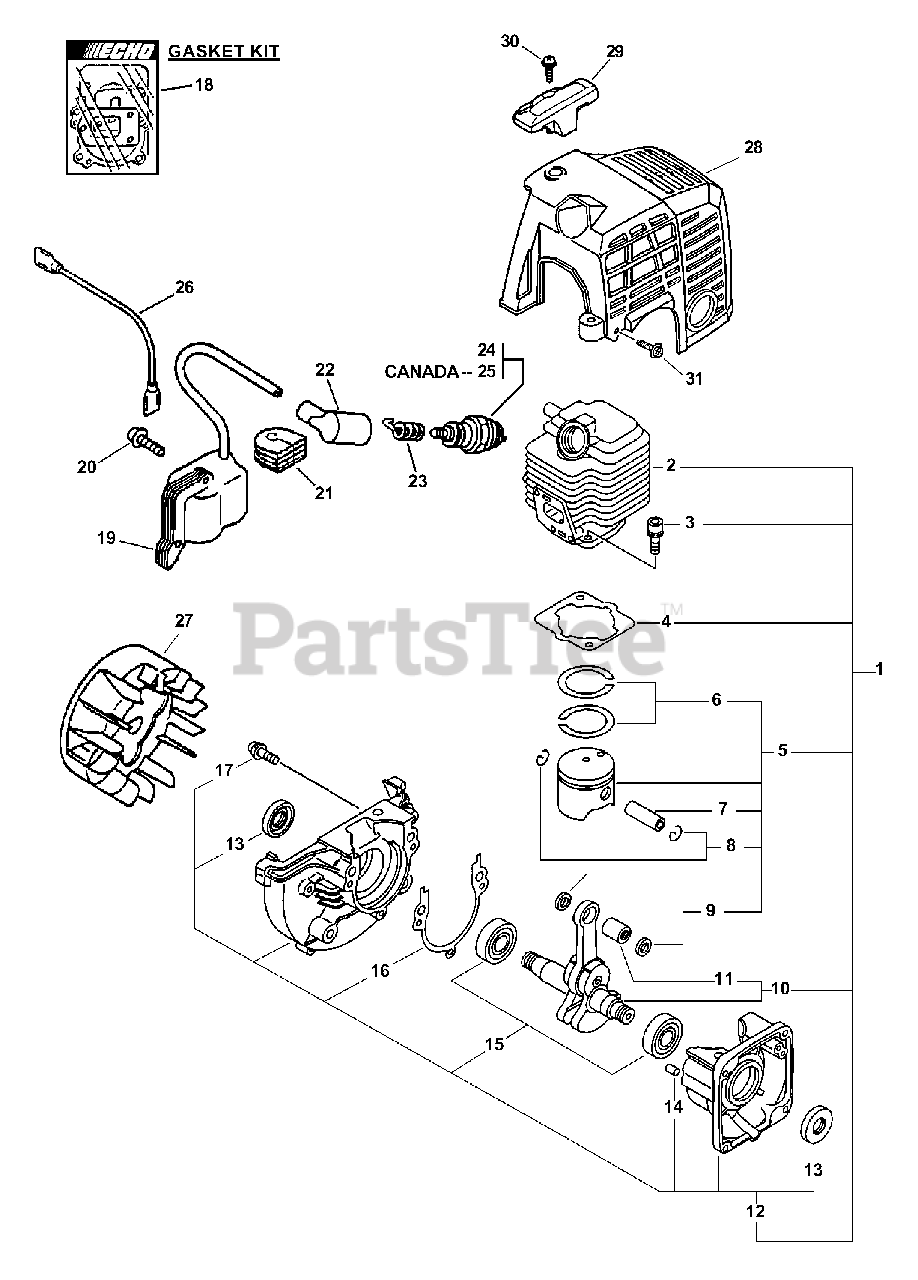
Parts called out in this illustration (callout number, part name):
1	SHORT BLOCK ES-2400
2	CYLINDER
3	BOLT 5×22
4	GASKET, CYLINDER
5	PISTON KIT
6	RING, PISTON
7	PIN, PISTON 8
8	RING, SNAP
9	WASHER, THRUST
10	CRANKSHAFT ASSY
11	BEARING, NEEDLE
12	CRANKCASE KIT
13	SEAL, OIL 12
14	PIN, LOCATING 4
15	BEARING, BALL - 6201 C3
16	GASKET, CRANKCASE
17	BOLT 5×28
18	GASKET KIT
19	COIL, IGNITION
20	SCREW 4×22
22	CAP, SPARK PLUG
23	TERMINAL, SPARK PLUG
24	SPARK PLUG - BPM-7Y
25	SPARK PLUG - RCJ7Y
26	LEAD
28	COVER, ENGINE
29	GUARD, TOP
30	SCREW 5×16
31	BOLT 4×16
